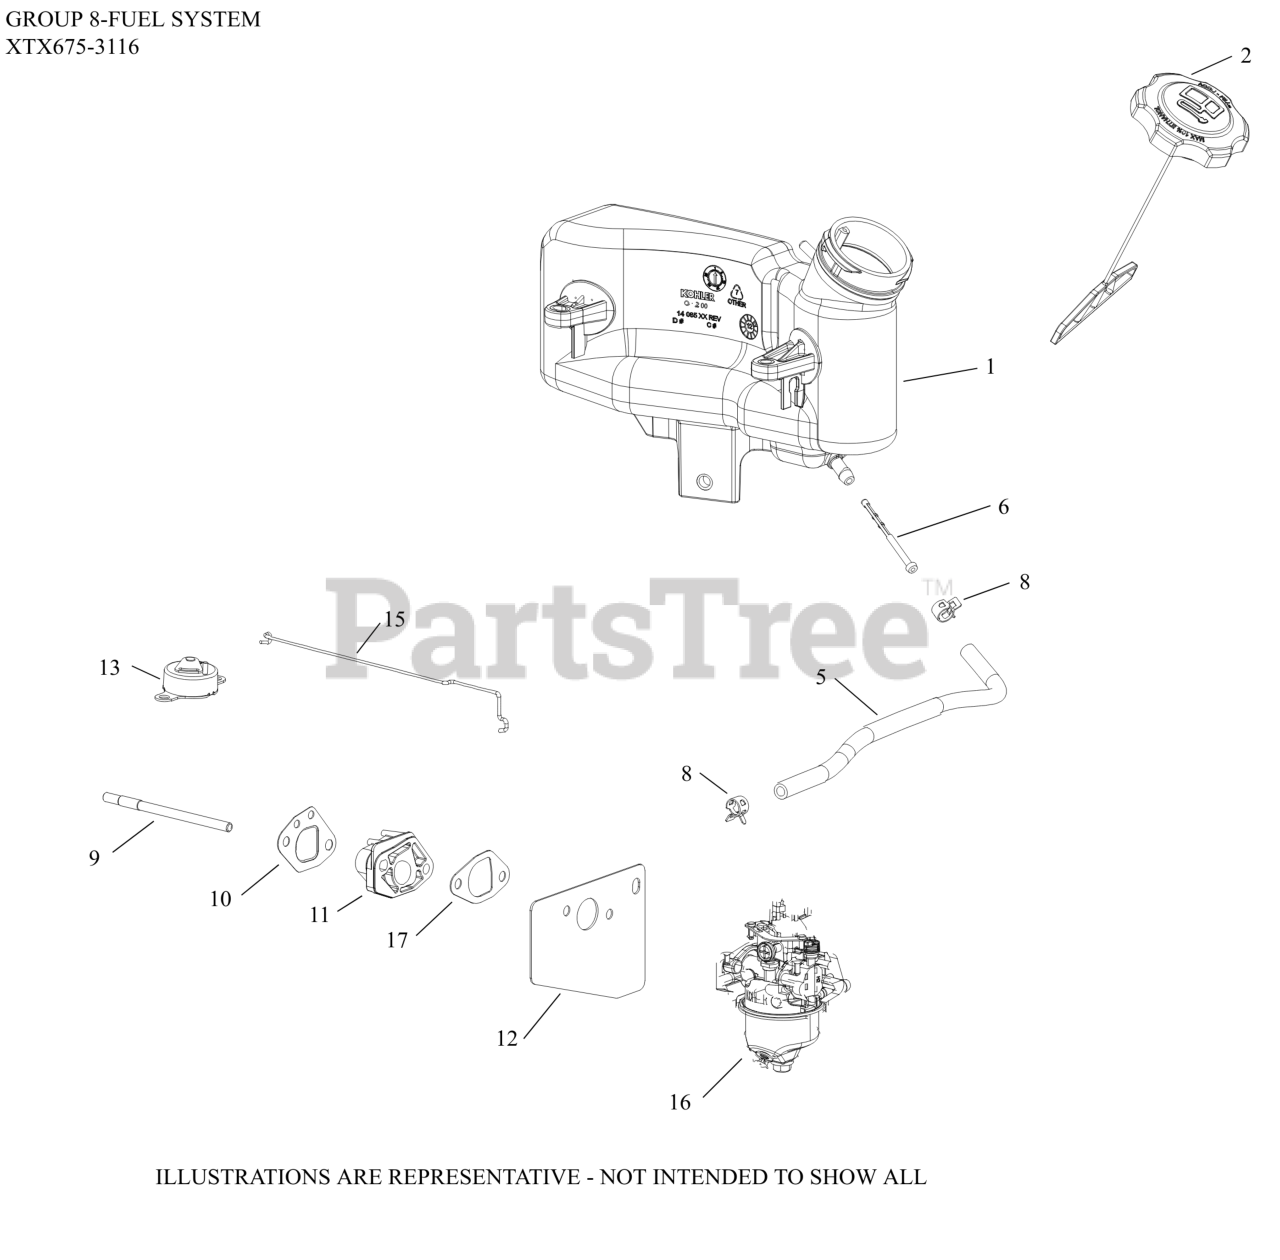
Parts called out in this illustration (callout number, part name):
1	TANK, FUEL
2	FUEL CAP ASSEMBLY
5	HOSE, FUEL LOW-PERMEATION (CKY)
6	FILTER, FUEL IN-NIPPLE
8	CLAMP, HOSE (NON-CALIF)(#1423710S)
9	STUD,M6X1.0X100.2MM
10	GASKET, SPACER - USE 14 041 24-S
11	SPACER, CARBURETOR
12	KIT, CARBURETOR HEAT SHIELD GASKET
13	ARM ASSEMBLY, AUTO CHOKE
15	LINKAGE, AUTO CHOKE
16	KIT,CARB (HUAYI)
17	KIT, INTAKE GASKET
NI	KIT, CARBURETOR REPAIR (HUAYI)
NI	KIT, HIGH ALTITUDE 4000-8000'
